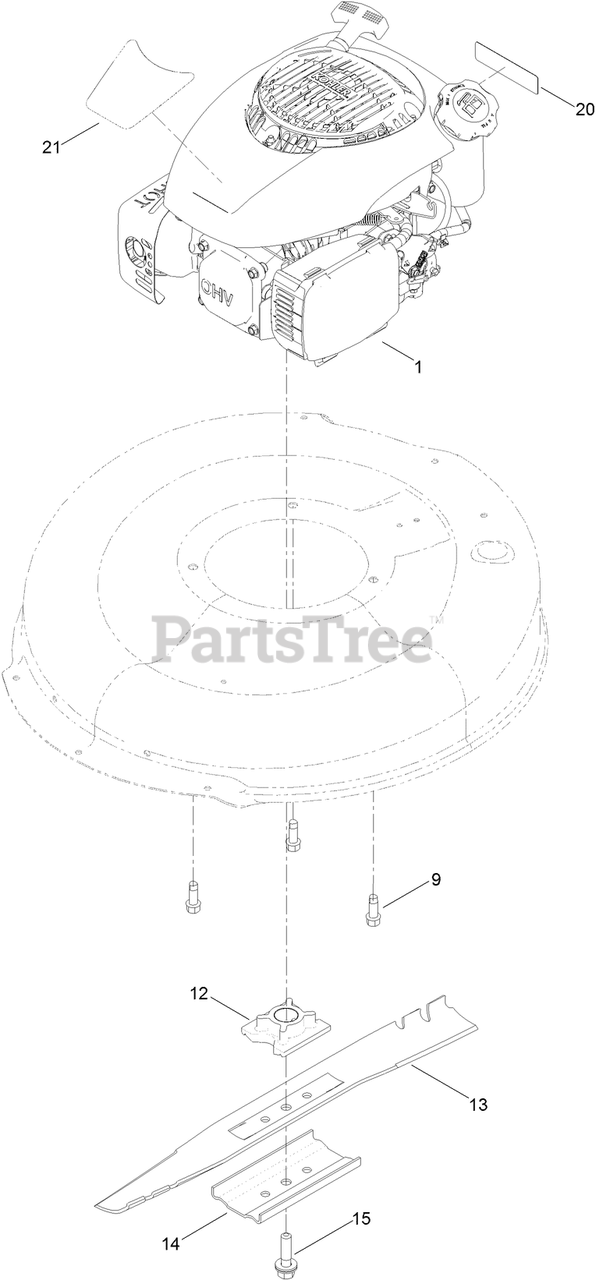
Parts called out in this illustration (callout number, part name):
9	SCREW-TAPTITE
12	RETAINER-BLADE
14	SUPPORT-BLADE
15	BOLT-BLADE
20	DECAL-ARRESTER, SPARK
